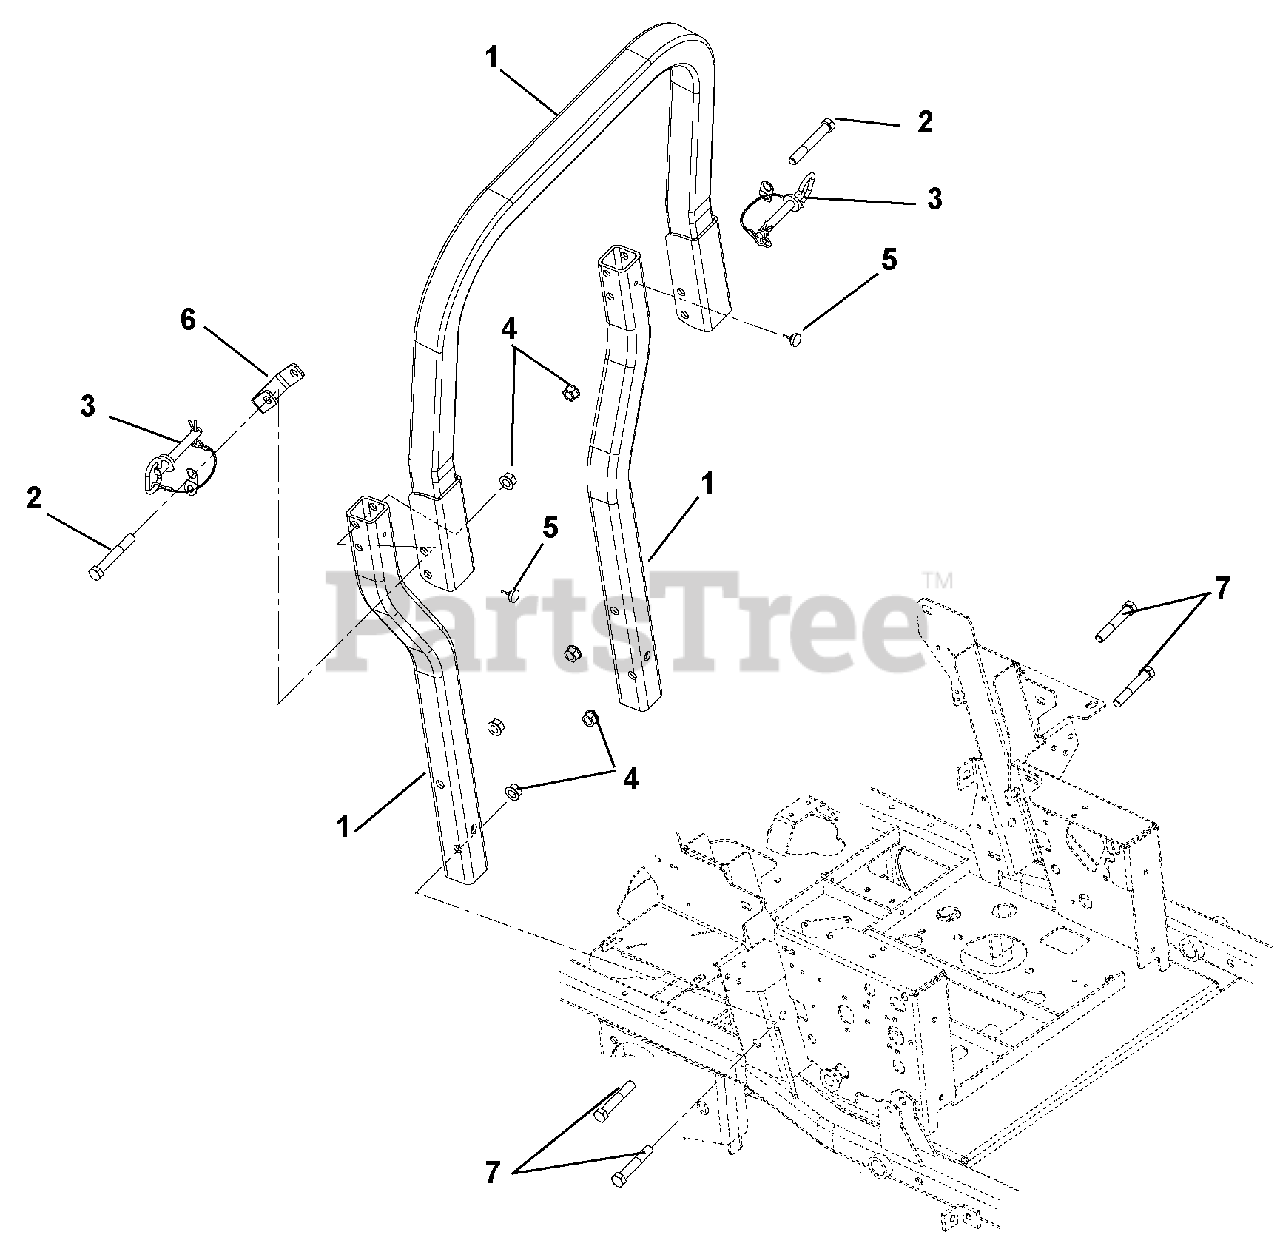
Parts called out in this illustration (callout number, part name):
1	ROPS, PM200 REPLACEMENT
2	@BLT-HEX .50-13X3.50 GR5 YWZC
3	ASSY, ROPS PIN/LANYARD
4	@NUT-LK-TOP-FLG .50-13 YWZC
5	BUMPER, ROPS RUBBER
6	BRKT, ROPS STOP,PRO-MASTER BLK
7	@BLT-HEX .50-13X3.00 GR5 YWZC
